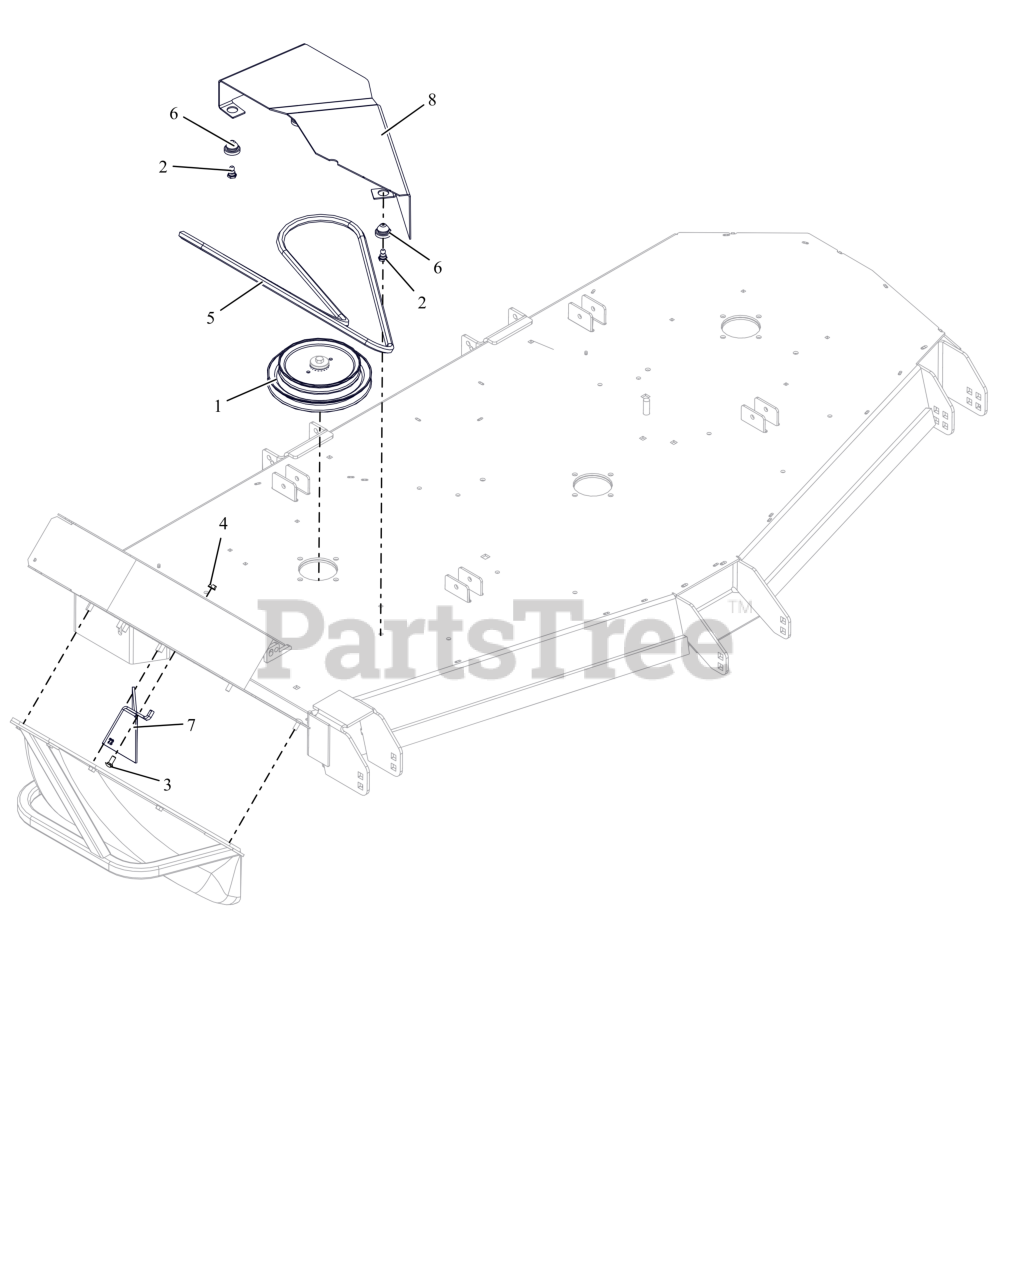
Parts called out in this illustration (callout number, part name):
1	SHV-DBL 1.00"IDX8.25"&6.50"OD
2	STUD, BALL FEMALE .250-20 THREAD
3	BLT, RHSSN.31-18X.750 G5 ZCC
4	NUT,LK-CTR-FLG .31-18 GF ZCC
5	HEX BELT, HAA SECTION
6	COUPLING, RUBBER PUSH-IN
7	BRKT, PT600 72" BAGGER DISCH (BLACK)
8	GUARD, RH 72" BLOWER DECK BELT (BLACK)
